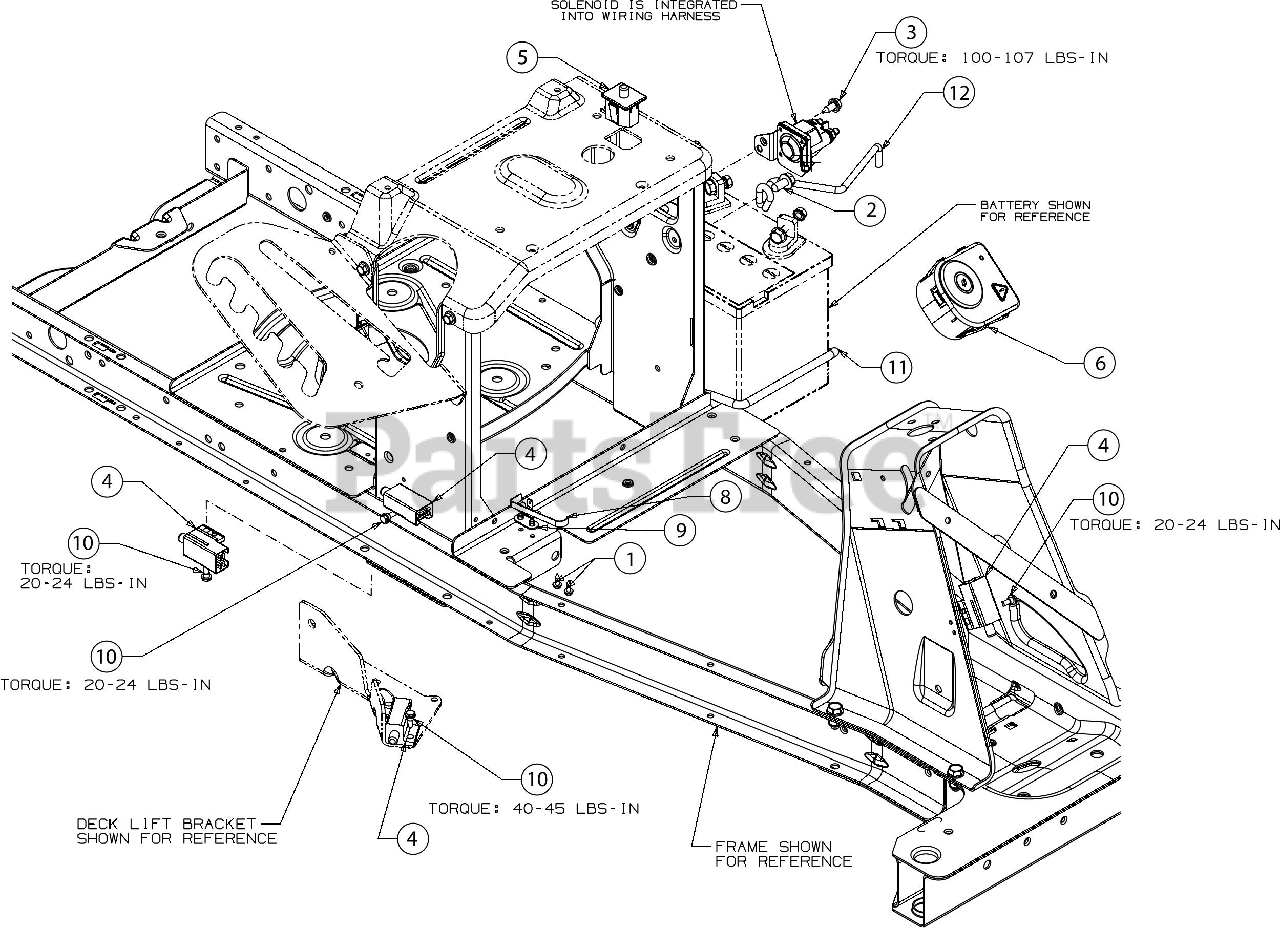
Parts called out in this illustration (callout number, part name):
1	HEX SCREW WASHER HD #8-18 x 0.500
2	SCREW 5/16-18 x .750
3	SCREW 1/4-20X.625
4	INTERLOCK SWITCH (NO/NC)
5	SEAT SWITCH
6	IGNITION MODULE SWITCH RMC (MAN PTO BLK)
8	SPRING SWITCH
9	INSULATOR PLATE
10	SHOULDER SCREW
11	BATTERY TRAY ROD
12	BATTERY HOLD DOWN ROD
